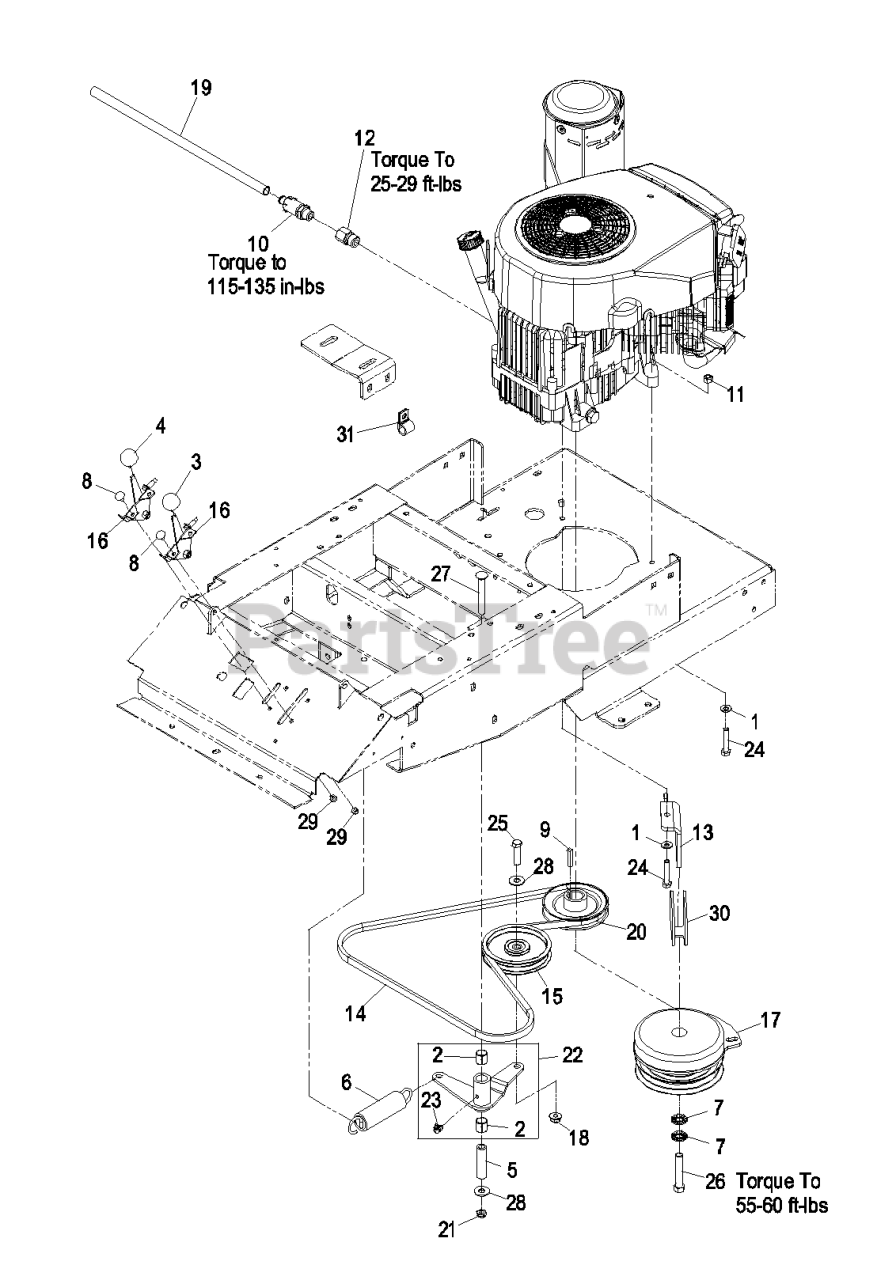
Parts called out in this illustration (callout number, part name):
1	WASHER-SPRING
2	SLEEVE-BEARING
3	KNOB-BALL
4	KNOB-BALL, BLACK
5	BUSHING-PIVOT, IDLER
6	SPRING-EXTENSION
7	WASHER-SPRING
8	BOLT-CARR
9	KEY-SQUARE
10	VALVE-DRAIN, OIL
11	NUT-LOCK, NI
12	ADAPTER
13	ROTATION-STOP, CLUTCH
14	BELT-V
16	THROTTLE CONTROL ASM
18	NUT-HF, NI
19	TUBE-DRAIN, OIL
22	IDLER HYDRO ASM
23	FITTING-GREASE, 90 DEG
24	SCREW-HH
25	SCREW-HH
26	SCREW-HH
27	SCREW-CARR
28	WASHER-FLAT
29	NUT-LOCK, NI
31	CLIP-LOOM
